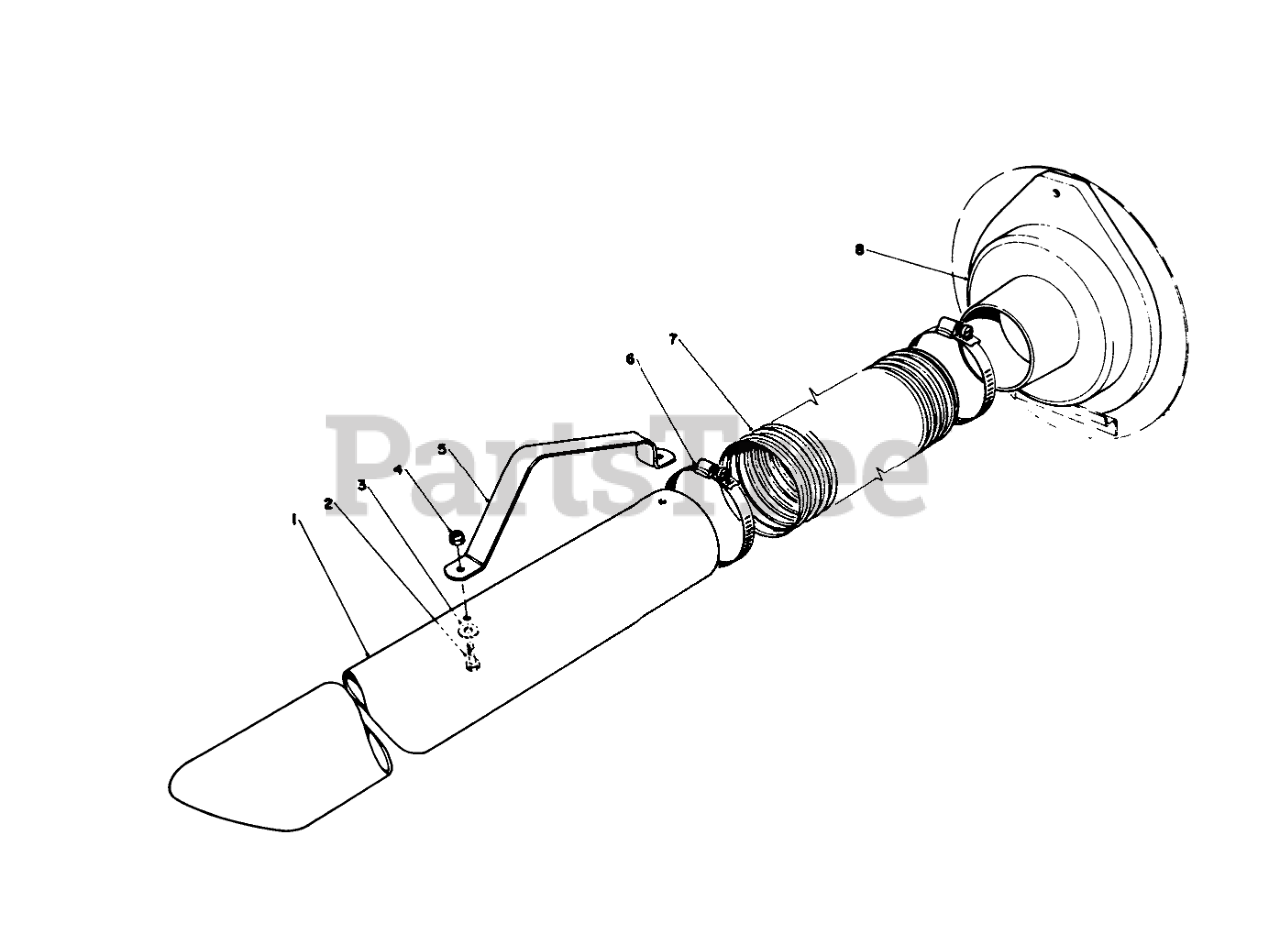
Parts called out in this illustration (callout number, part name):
1	NOZZLE
2	SCREW-HH
3	SPECIAL WASHER
4	NUT-KEPS
5	NOZZLE HANDLE
6	CLAMP
7	VACUUM HOSE
8	ADAPTOR HOSE TO HSG
